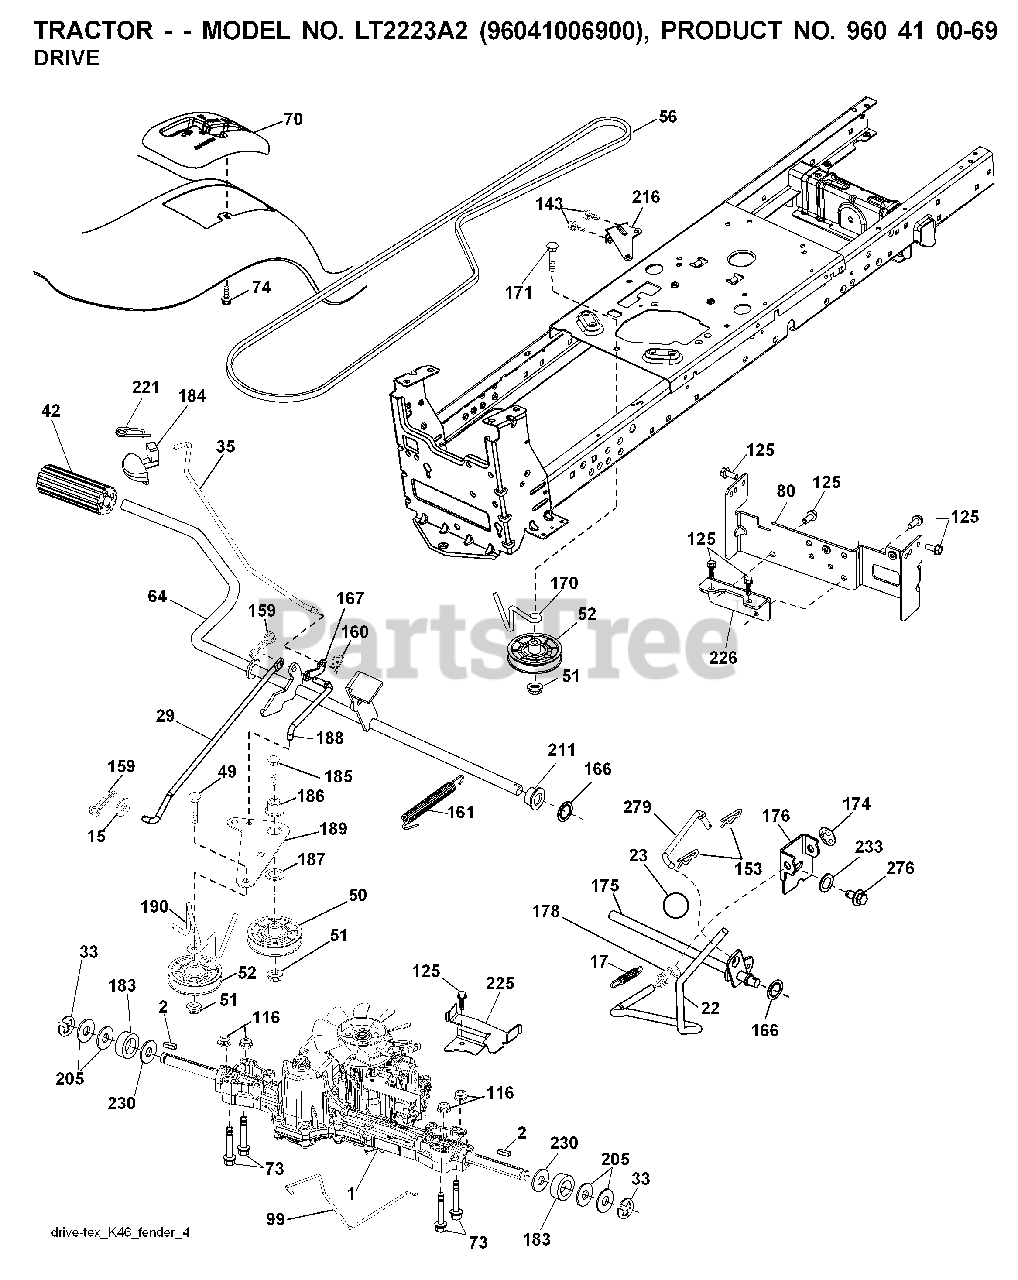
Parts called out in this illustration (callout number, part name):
2	SQUARE KEY
17	SPRING.BRAKE.K46.GREEN
22	ROD.SHIFT.FENDER.TLT.2006
23	PISTOL KNOB
29	ROD.BRAKE.K46
33	E-RING LT
35	ROD.BRAKE.PARKING.LT.T
42	PEDAL COVER T
49	BOLT
50	IDLER.FLAT.910.OFFSET
51	NUT LOCK FLG 3/8-16 UNC
52	IDLER.V-GROOVE.910.OFFSET
64	SHAFT.ASM.PEDAL.BRAKE.
70	CONSOLE.SHIFT.STL.HYD.BLACK
73	BOLT HEX 5/16-18 GR 5
74	SCREW.HI-LO.CONSOLE
80	STRAP TORQUE
99	ROD.SPRING.BYPASS.K46.LT.Z
116	NUT LOCK HEX FLANGE 5/16-18
125	SCREW
153	RETAINER M
159	COTTER PIN
160	RETAINER CLIP
161	SPRING, RETURN LT
162	SPACER.TRANSAXLE.18&22
166	NUT.PUSH.625.2006
167	LATCH.BRAKE.SPRING
170	KEEPER.V-IDLER.CENTER.
171	BOLT
174	NUT.PUSH.500.2006
175	SHAFT ASM SHIFT
176	ARM.CLEVIS.ROD.SHIFT
178	SPRING.SHIFT.GT2006
183	SPACER AXLE
184	HANDLE.PAKRING.BRAKE.
186	SPACER.RETAINER
187	WASHER 12/32X2X10GA
188	LINK.CLUTCH.GROUND.DRIVE
189	BELLCRANK.GROUND.DRIVE.TEX.
190	KEEPER.BELLCRANK.DRIVE
211	BUSHING.SHAFT.BRAKE.HAND
216	BRACKET.PULLEY.IDLER.W/TEX
221	RETAINER.SPRING.CLIP.H
225	KEEPER.BELT.TRANSAXLE.K46
226	BRACKET.MOUNT.TORQUE.K46.TLT
230	WASHER.HARDENED
233	WASHER SERRATED
276	BOLT FIN HEX 7/16-14 X 1
279	LINK SHIFT
